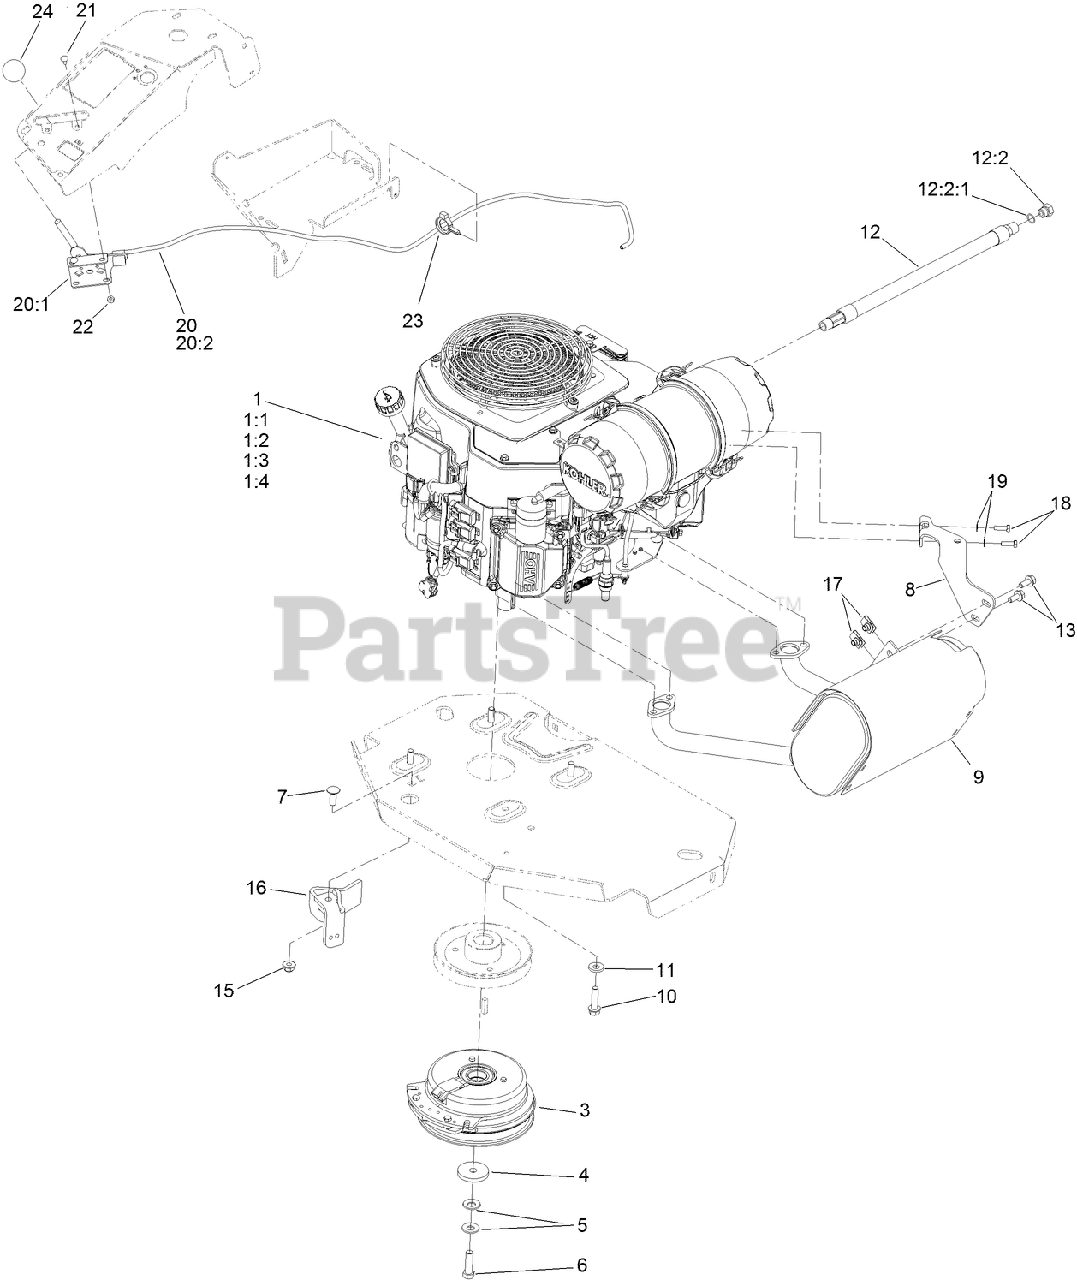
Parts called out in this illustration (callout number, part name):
1:1	KOHLER 52 050 02-S ENGINE OIL FILTER
1:2	KOHLER 25 083 01-S ENGINE AIR FILTER
1:3	KOHLER 25 083 04-S SAFETY FILTER
1:4	KOHLER 25 050 50-S Propane Fuel Filter
3	CLUTCH KIT
4	WASHER-CLUTCH
5	WASHER-SPRING
6	SCREW-HH, W/LOCTITE
7	SCREW-CARR
8	MUFFLER BRACKET KIT
9	MUFFLER KIT
10	SCREW-HWH
11	WASHER-BELLEVILLE
12	OIL DRAIN HOSE ASM
12:2	PLUG-HH
12:2:1	O-RING
13	SCREW-HH
15	NUT-HF, NI
16	CLUTCH-ANCHOR
17	NUT-U
18	SCREW-HH
19	WASHER-SPRING
20	THROTTLE CONTROL ASM
20:1	LEVER-THROTTLE
21	BOLT-CARR
22	NUT-LOCK, NI
23	CLAMP-HOSE
24	KNOB-BALL
